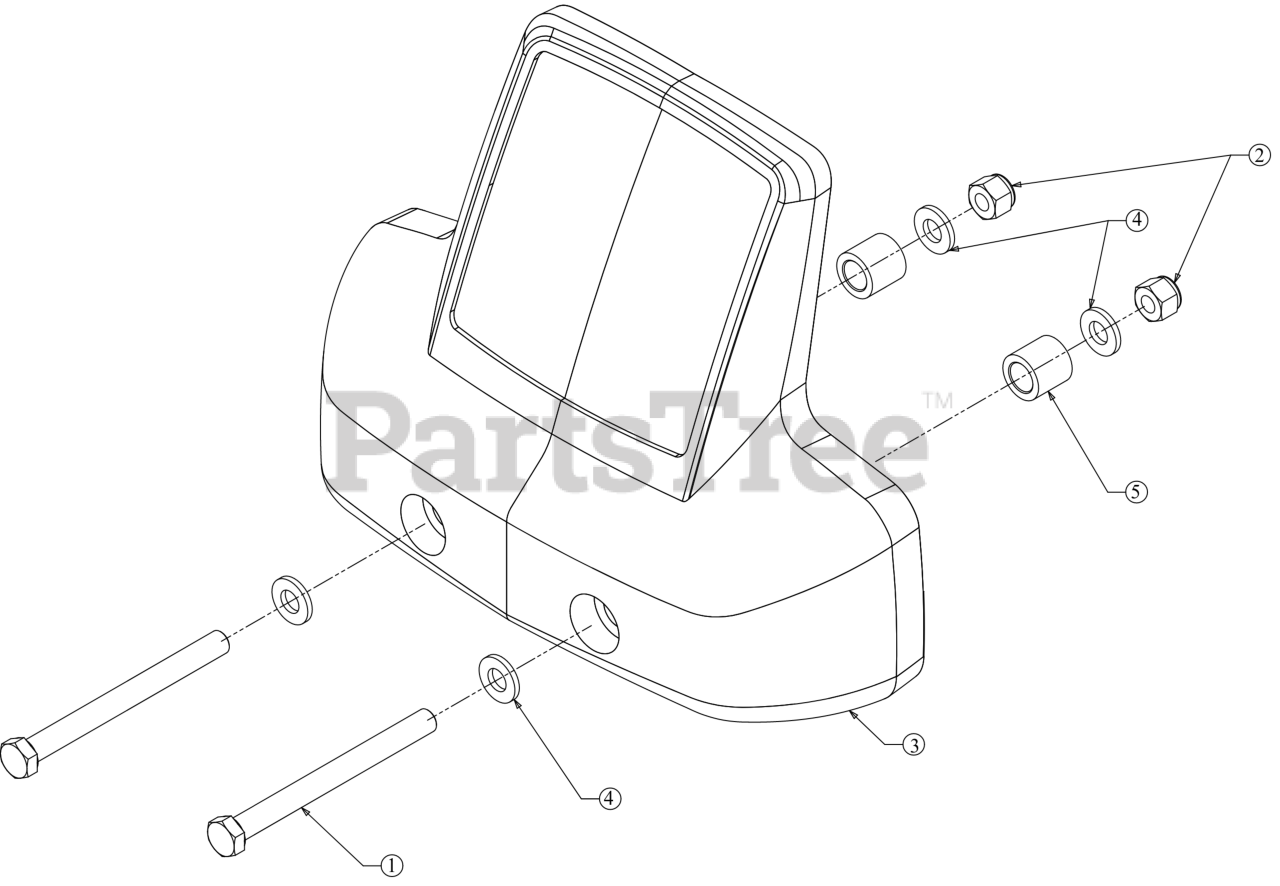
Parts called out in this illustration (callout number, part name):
1	SCREW 1/2-20 X 5.50 GR5
2	HEX NUT CENTER
3	COUNTER WEIGHT
4	FLAT WASHER .510 X 1.000 X .125
